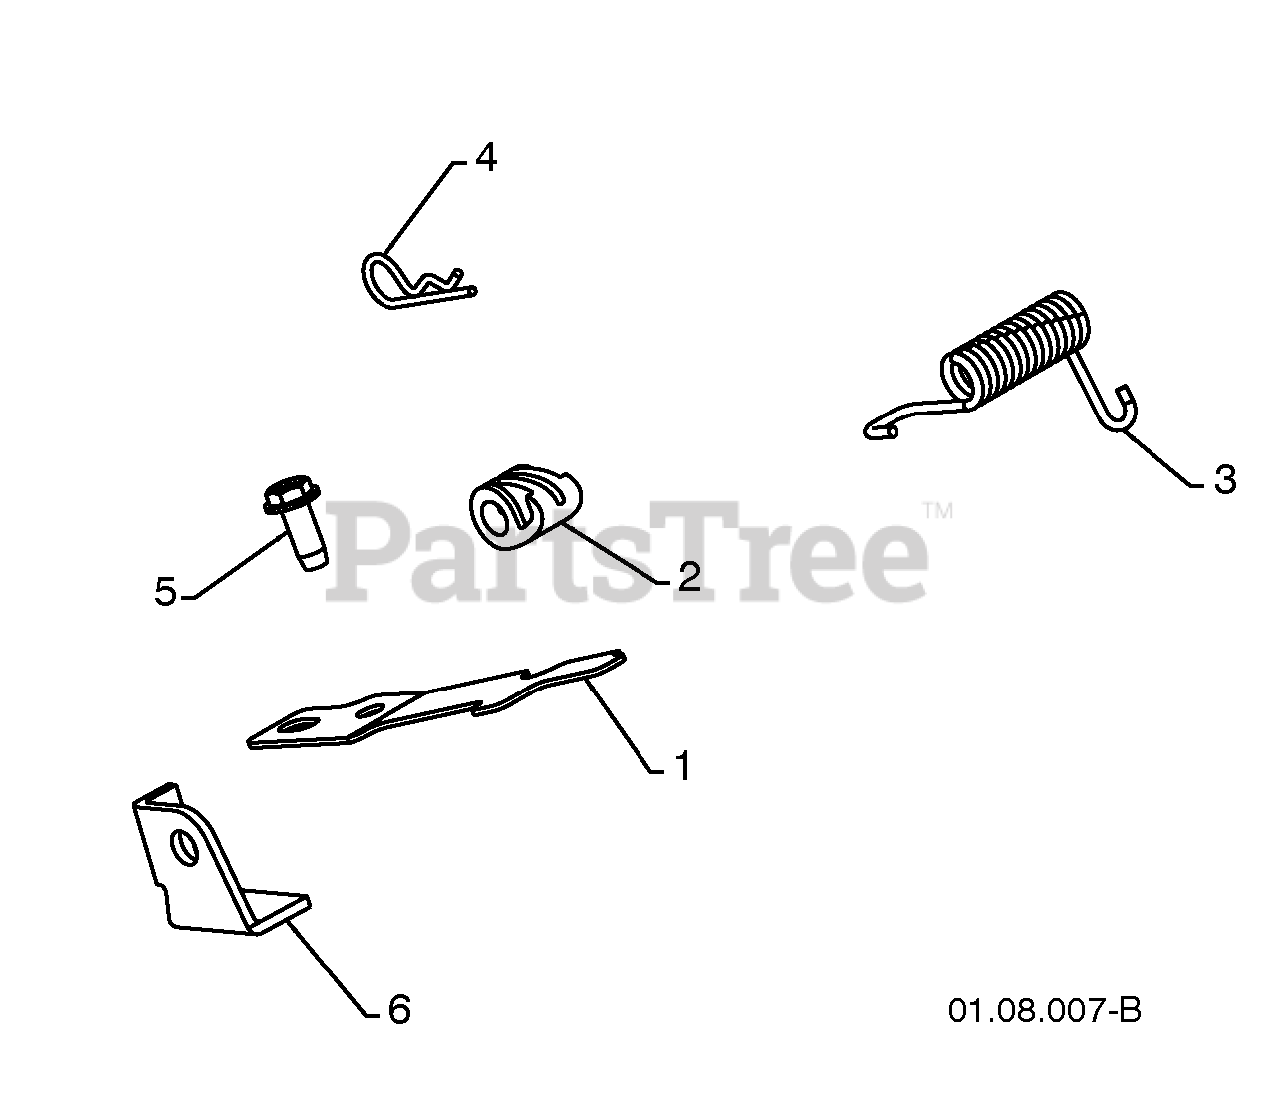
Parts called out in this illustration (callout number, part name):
1	INTERLOCK SPRING
2	INTERLOCK CAM
3	TORSION SPRING
5	SCREW 1/4-20 X .625
6	INTERLOCK STOP
